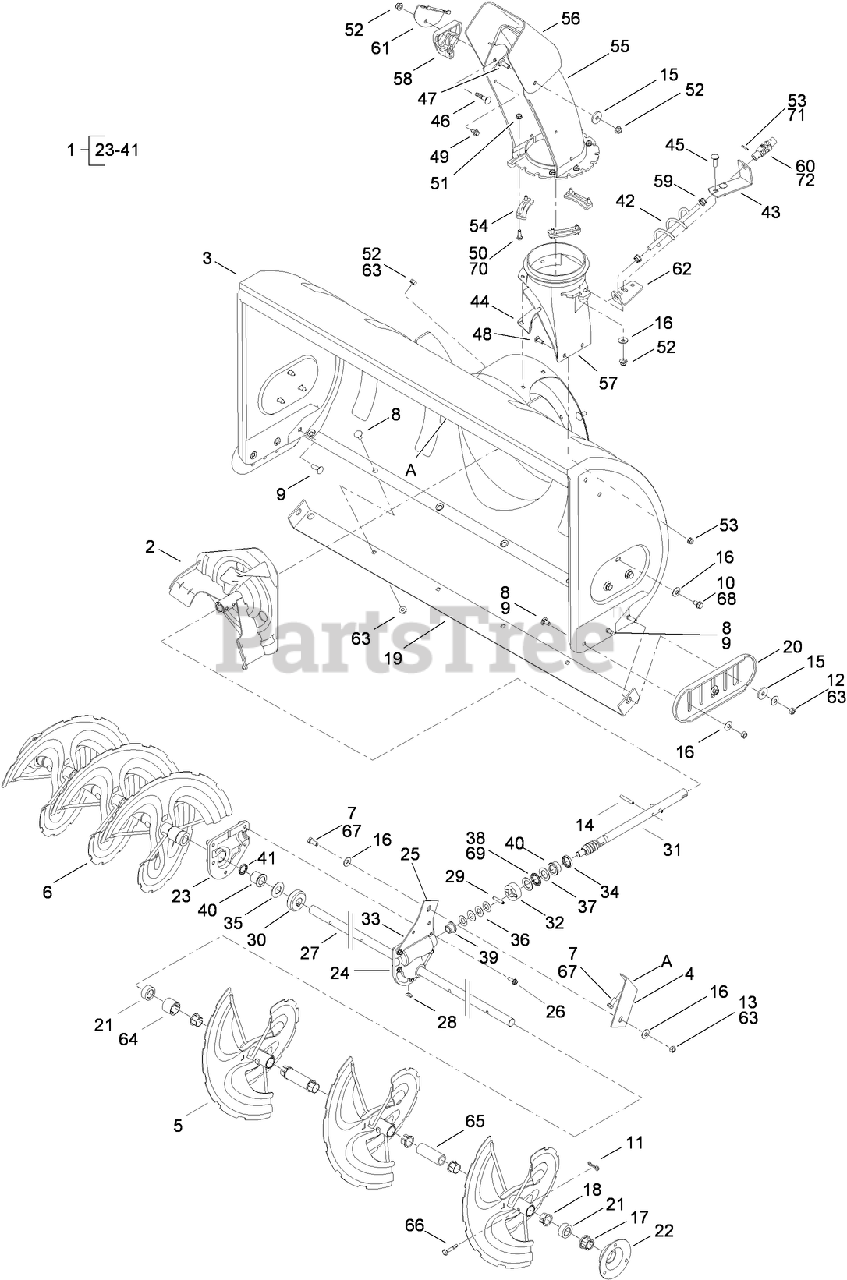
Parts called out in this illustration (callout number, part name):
1	AUGER GEARBOX ASM
2	IMPELLER ASM
3	HOUSING ASM
4	BRACKET-HOUSING, BRACE
5	LH SPIRAL AUGER ASM
6	RH SPIRAL AUGER ASM
7	SCREW-HH
8	BOLT-CARR
9	BOLT-CARR
10	BOLT-CARR
11	PIN-COTTER
12	NUT-HEX
13	NUT-HEX
14	PIN-ROLL
15	WASHER-FLAT
16	WASHER-BELL
17	BEARING-FLANGE
18	BEARING-FLANGE
19	BRACKET-PLATE, SKID
20	SHOE-SLIDE
21	SPACER
22	HOUSING-BEARING, HEX
23	HOUSING-REDUCER, RH
24	HOUSING-REDUCER, LH
25	PLATE-BRACE, HOUSING
26	SCREW-TAP
27	AXLE-SPIRAL
28	KEY-HI PRO
29	PIN-SPIROL, SPRING
30	GEAR-WORM, 20T
31	SHAFT-WORM
32	COLLAR-THRUST
33	PLUG-GREASE
34	SEAL-GREASE
35	WASHER-THRUST
36	WASHER-FLAT
37	WASHER-THRUST
38	BEARING-THRUST
39	BEARING-FLANGE
40	BEARING-FLANGE
41	SEAL-GREASE
42	CRANK CHUTE ASM
43	BRACKET-CHUTE
44	REINFORCEMENT-CHUTE
45	BOLT-CARR
46	BOLT-CARR
47	BOLT-CARR
48	BOLT-CARR
49	SCREW-HH
50	SCREW-HH
51	NUT-LOCK, FLANGE
52	NUT-LOCK, FLANGE
53	PIN-SPRING, SPIRAL
54	KEEPER-FLANGE, CHUTE
55	CHUTE-LOWER
56	CHUTE-UPPER
57	ADAPTER-CHUTE, DISCHARGE
58	GUIDE-CABLE
59	BEARING-BALL
60	JOINT BLOCK ASM
61	BRACKET-CABLE
62	BRACKET-CRANK, CHUTE
63	NUT-LOCK, FLANGE
64	SPACER
65	SLEEVE
66	PIN-SHEAR
68	SCREW-TAP
69	BEARING-THRUST
70	SCREW-HEX
71	PIN-SPIROL
72	JOINT BLOCK ASM
